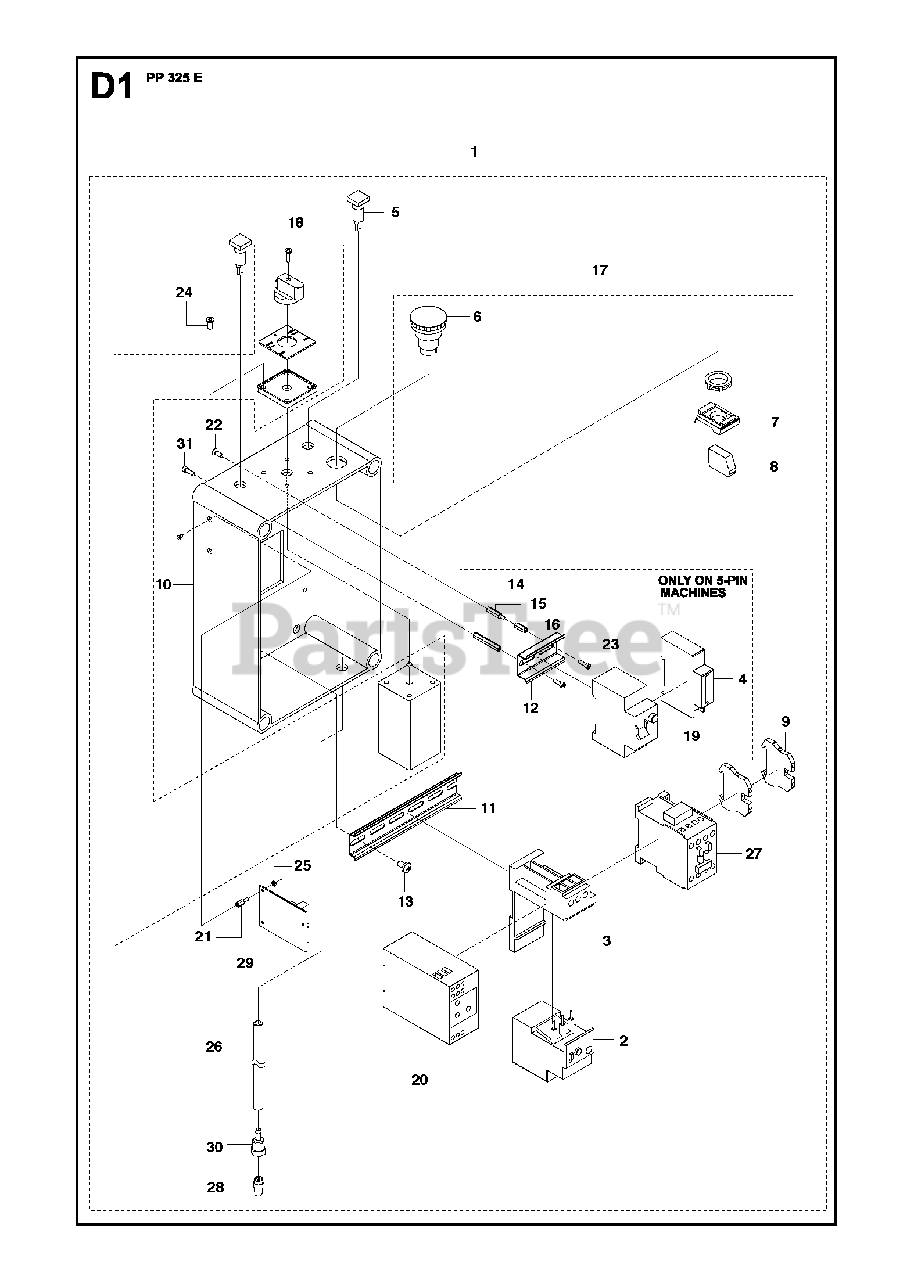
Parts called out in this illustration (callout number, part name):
1	ELECTRIC BOX400 V, 5-pin
1	ELECTRIC BOX400 V, 4-pin
1	ELECTRIC BOX480 V, 4-pin
4	HOUR METEROnly 5-pin machines
14	NUTOnly 5-pin machines
15	NUTOnly 5-pin machines
16	NUTOnly 5-pin machines
19	GUARDOnly 5-pin machines
23	SCREW IHSCMOnly 5-pin machines
